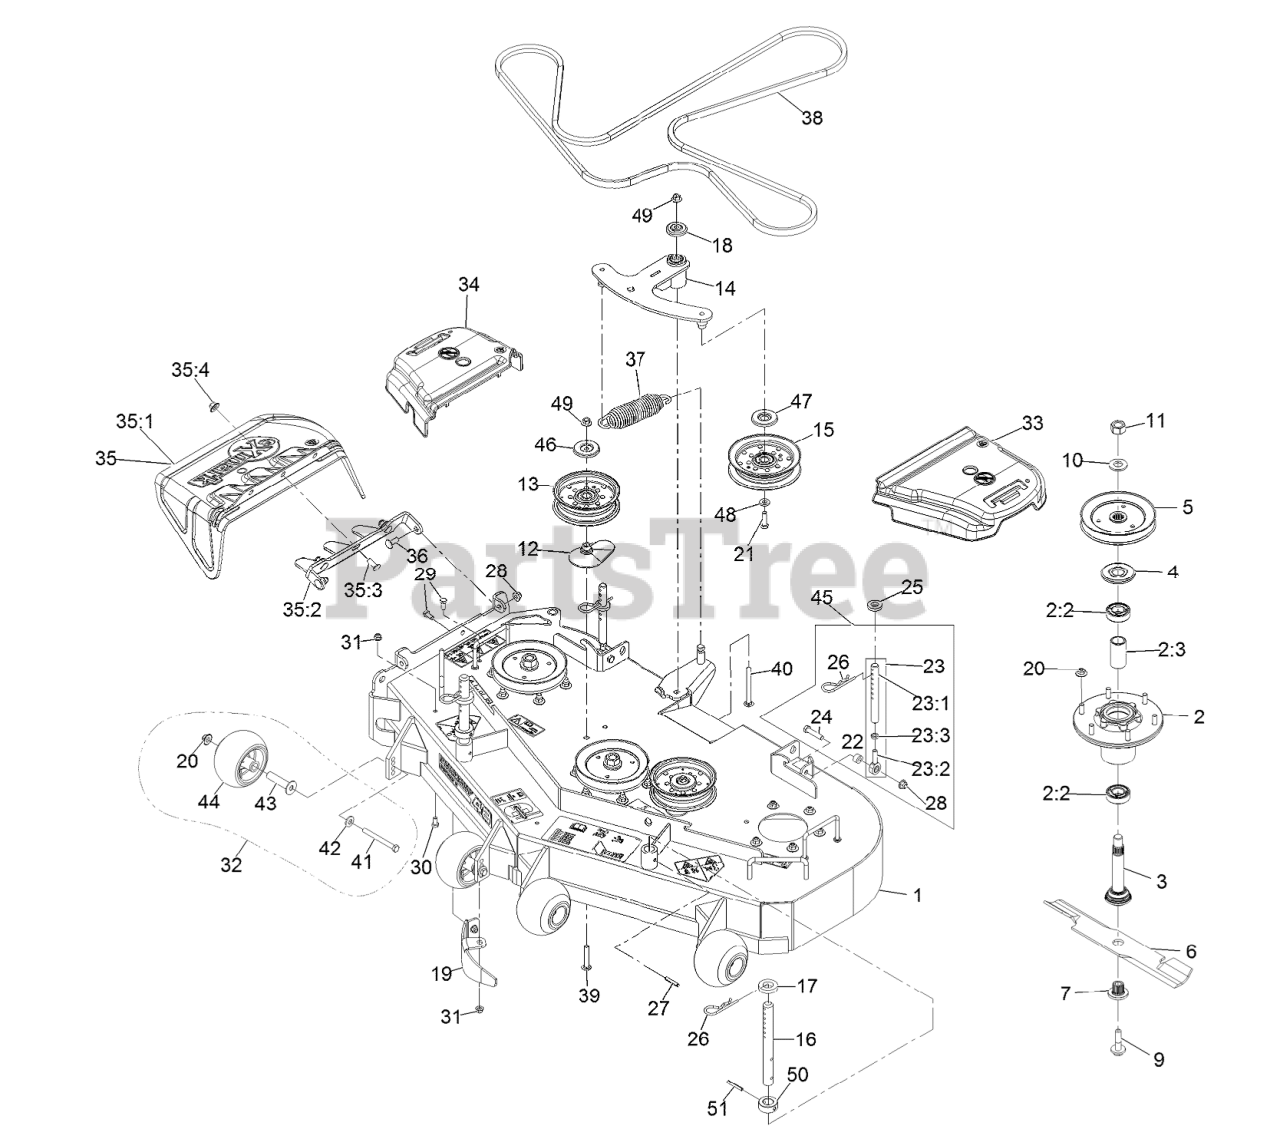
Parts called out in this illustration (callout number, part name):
1	ASM, DECK 48" W/DECALS
2	ASM-CUTTER HSG WITH BEARINGS
2:2	BEARING-BALL
2:3	SPACER-BEARING
3	ASM-SPINDLE AND SEAL
4	GUARD,BEARING TOP .989
5	SHEAVE,BLADE DRIVE 5.90
7	BUSHING,SPLINED
9	SCREW,SEMS 1/2-20 X 2.19
11	NUT-HEX
12	SPACER-PULLEY
13	IDLER-PULLEY, FLAT 5.00X1
14	ASM, DECK IDLER
15	IDLER-PULLEY, FLAT
16	Rod, Deck Support
17	SPACER-DECK SUPPORT
18	GUARD-TOP
19	BAFFLE, DOGLEG
20	Nut-Nyloc 3/8-16 Flg
21	SCREW-HH
23:1	LINK,SUPPORT
23:2	BALLJOINT
23:3	NUT-HJ
24	SCREW-HH
26	PIN,HAIR COTTER
28	NUT-HF, NI
29	SCREW-HH
30	SCREW-HH
31	NUT-HF, NI
32	KIT, ANTI-SCALP ROLLER
33	COVER-BELT, LH
34	COVER-BELT, RH
35	ASM, DISCHARGE CHUTE
35:1	CHUTE,DISCHARGE
35:2	BRACKET, DISCHARGE CHUTE
35:3	SCREW-CARR
35:4	Nut-Nyloc 3/8-16 Flg
36	SCREW-CARR
37	SPRING-EXTENSION
38	BELT, DECK
39	BOLT-CARR, SHORT NECK
40	SCREW-CARR
41	SCREW-HH 3/8-16 X 3 3/4 GR 8
42	WASHER-BELLEVILLE
43	AXLE, ROLLER
44	ROLLER-SCALP, ANTI
45	KIT,SUPPORT LINK W/PIN
46	SHIELD-DUST
47	SHIELD-GUARD, DUST
50	Collar, Deck Height Pin
51	PIN-ROLL
